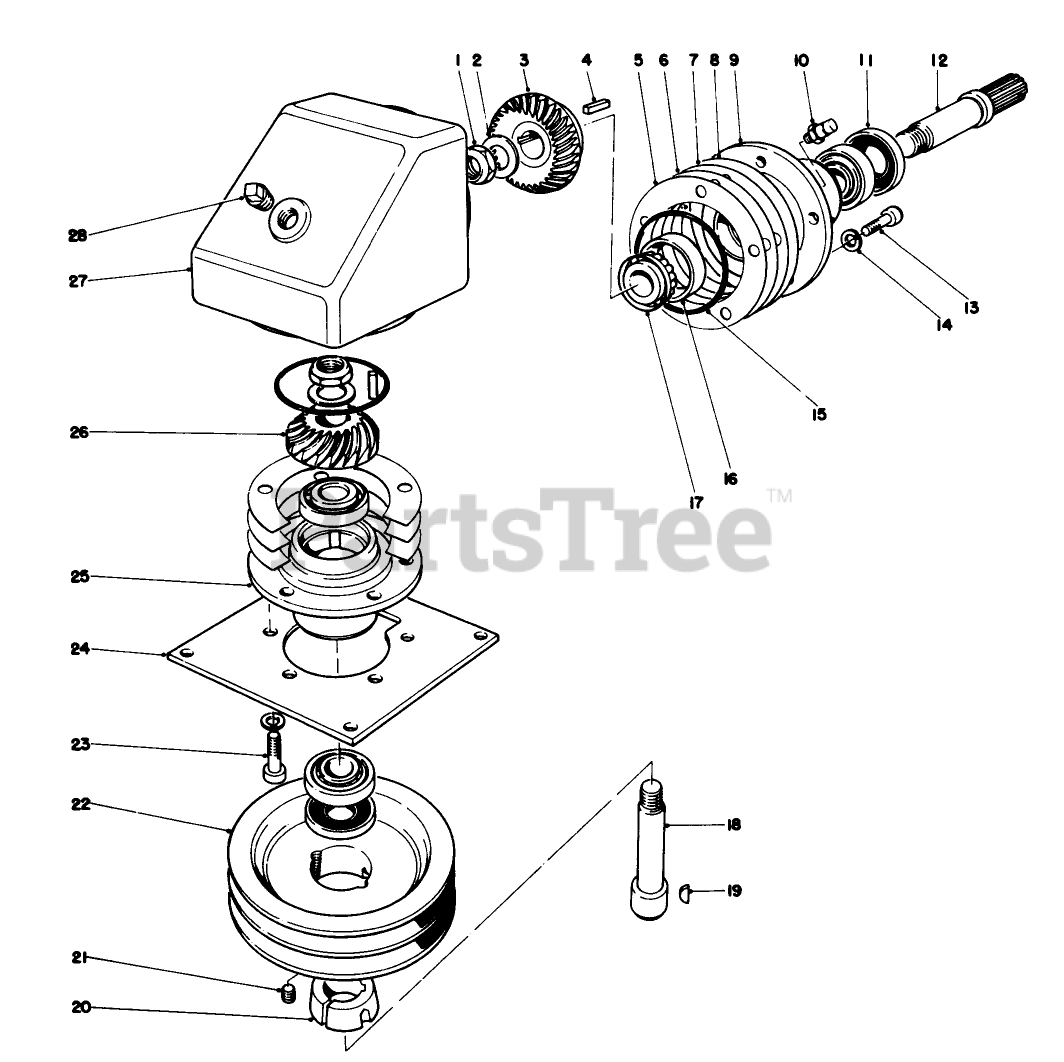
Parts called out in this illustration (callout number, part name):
1	NUT-LOCK, NI
2	THRUST WASHER
4	KEY-SQUARE
5	.002 SHIM (RED)
6	.005 SHIM (BLUE)
7	.015 SHIM (PINK)
9	INPUT BRG HSG
11	OIL SEAL
12	INPUT SHAFT
13	SCREW-HSH
14	WASHER-LOCK
15	O-RING
16	BEARING-CUP
17	CONE-BEARING
18	OUTPUT SHAFT
19	KEY-WOODRUFF
20	Bushing-Taper Lock (Incl. Ref. #21)
21	SCREW-SET
22	PULLEY-DECK
23	SCREW-HSH
24	GEAR BOX MTG PLT R
25	OUTPUT BRG HSG
26	PINION
27	GEAR BOX
28	3/8-18 SQ HD PLUG/MAG
